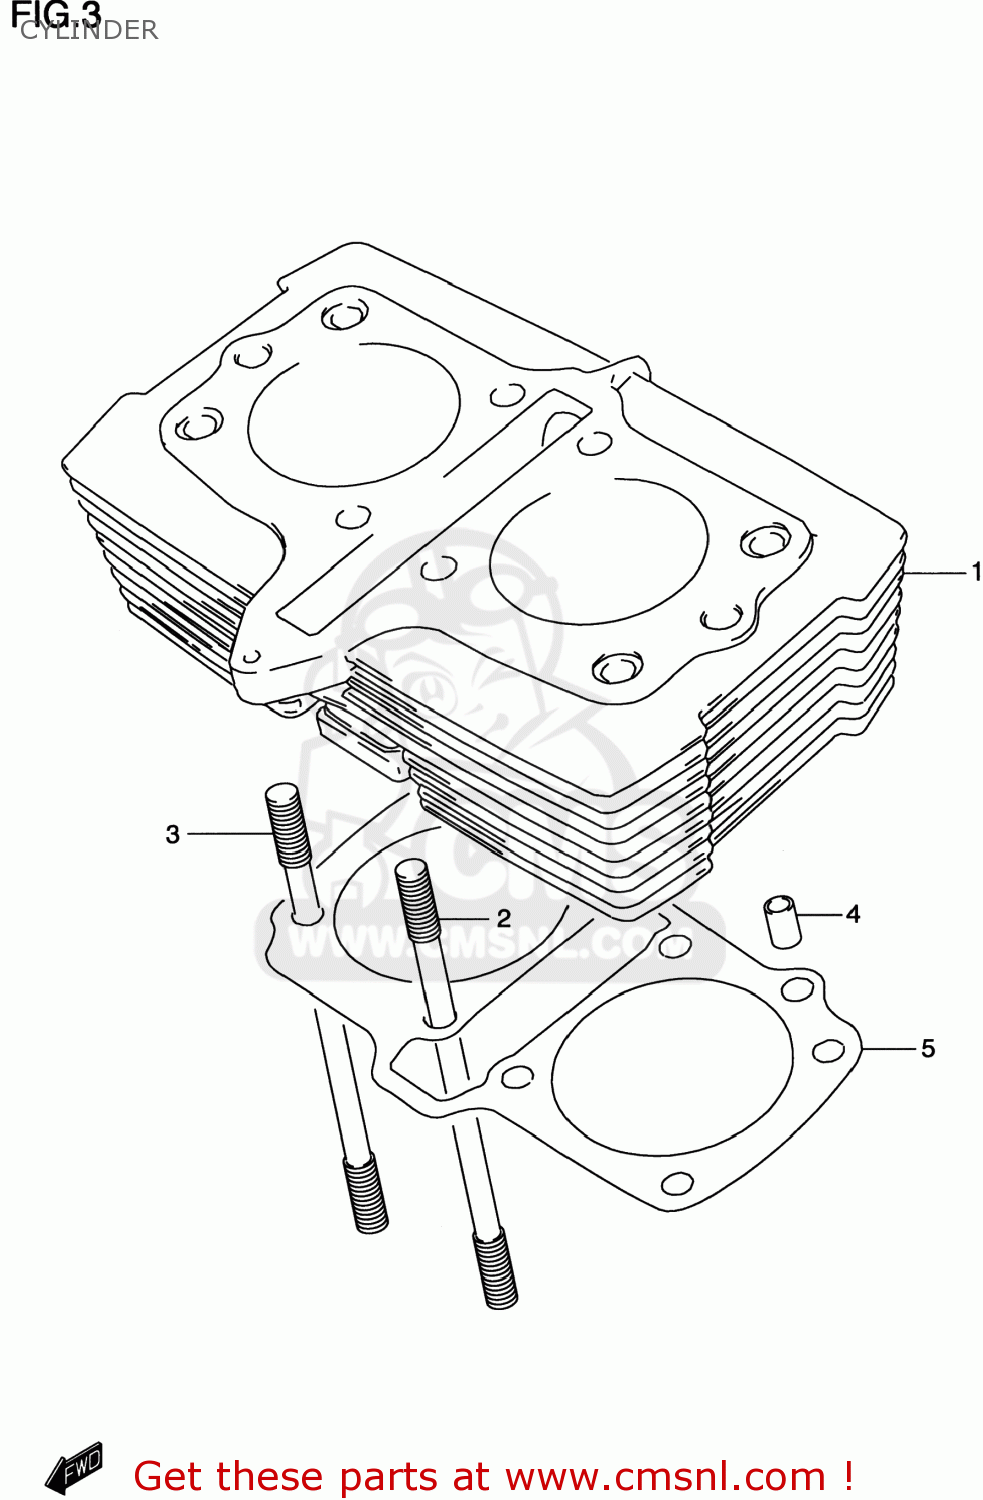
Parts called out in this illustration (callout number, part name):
1	CYLINDER
2	BOLT,STUD
3	BOLT,STUD
4	PIN
5	GASKET,CYLINDER (NAS)
